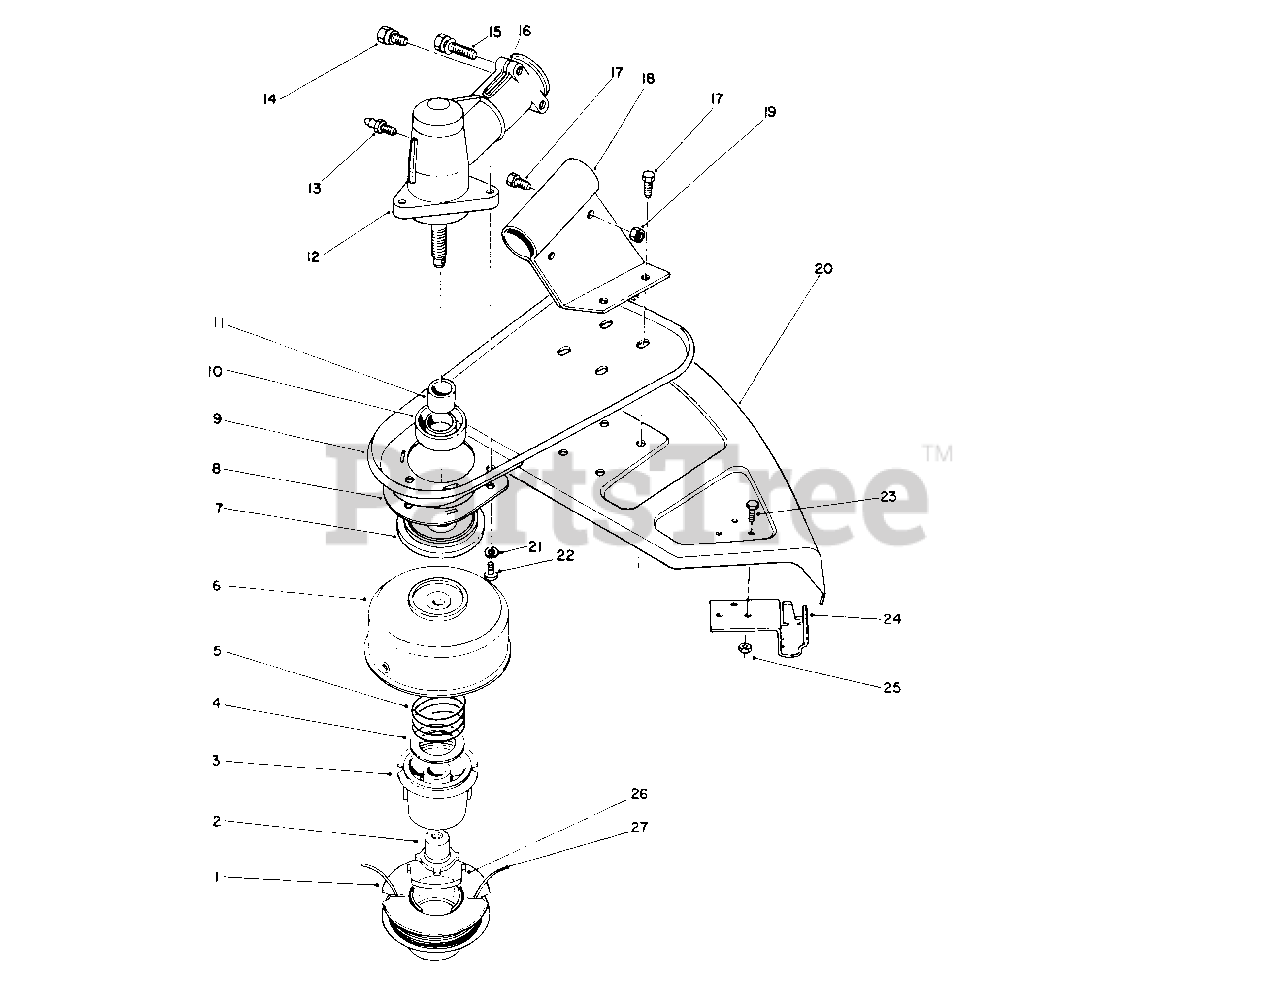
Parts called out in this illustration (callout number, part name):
1	Spool-Prewound (Incl. Ref. #26)
2	Driver L.H.
3	Core-Spool
7	Cap-Dust
8	Guard-Grass Wrap
9	Support-Shield
10	Seal-Oil
11	Sleeve-Spline
12	Gear Box Assembly (Incl. Ref. #10, 11, & 13-16)
13	Fitting-Grease
14	Screw-Hex. Hd. Cap
15	Screw-Hex. Hd. Cap
16	Washer-Flat
17	Screw-Hex. Hd. Cap
18	Bracket-Shield
19	Nut-Lock
20	Shield-Grass
21	Washer-Lock
22	Screw-Guard
24	Brace & Knife Blade Ass'y (Incl. Ref. #23-25)
25	Nut-Lock
26	Saddle-Spool Cap
27	Line-Cutting .08 Dia. 38'
